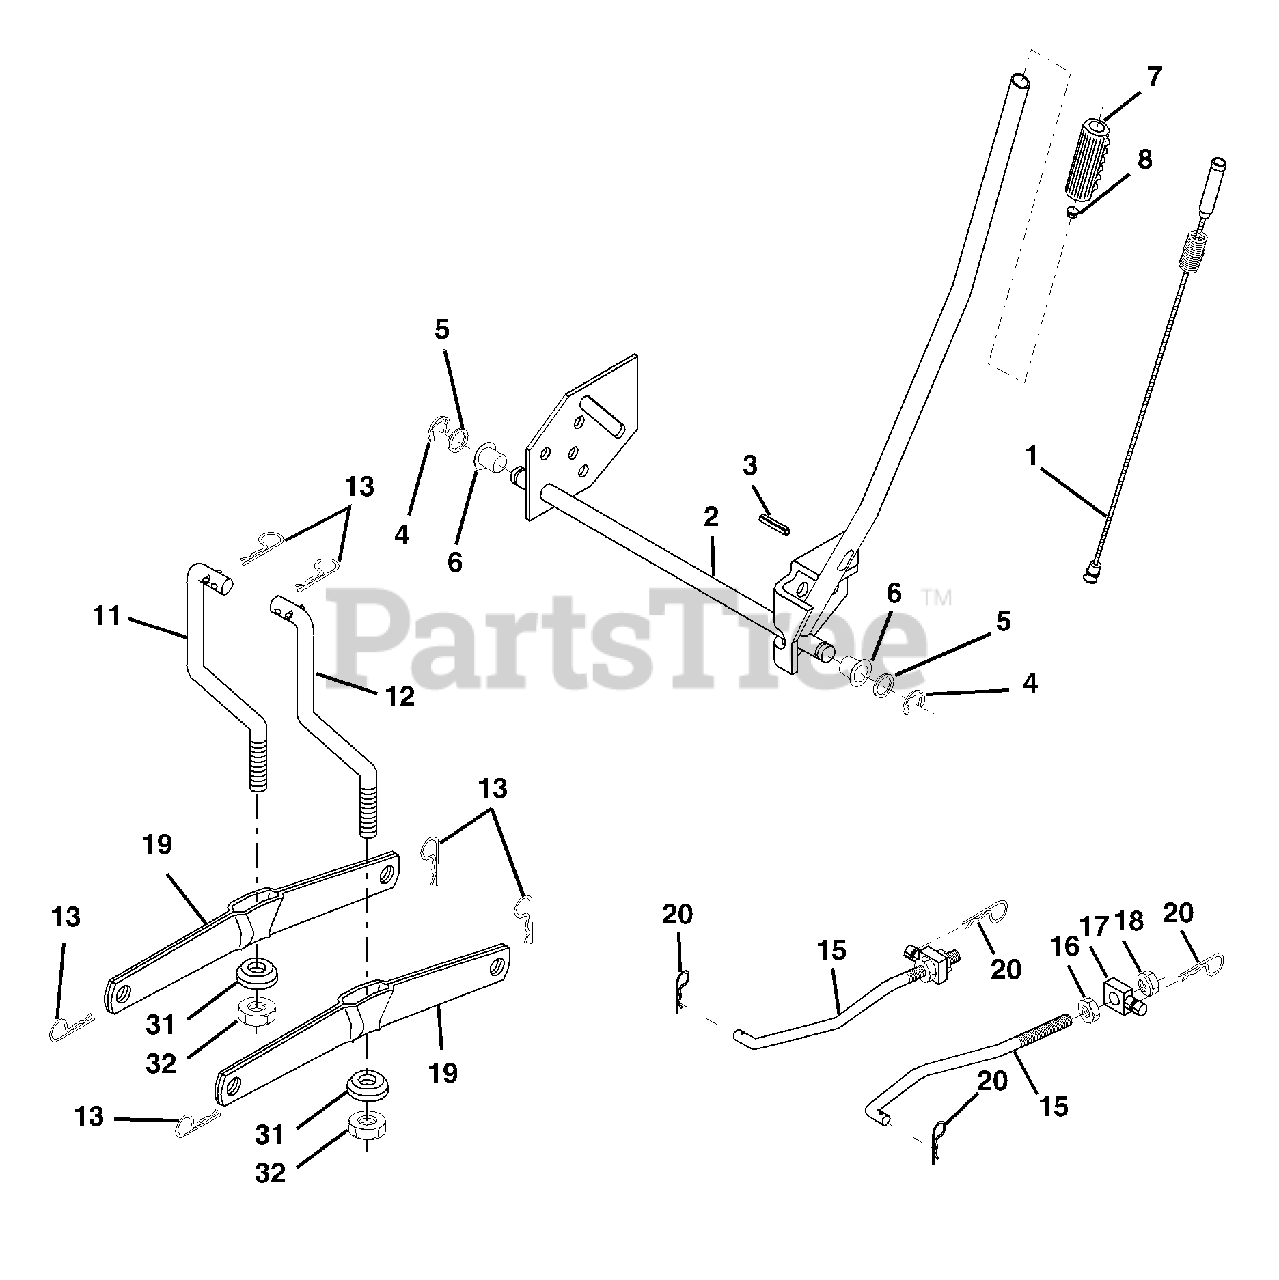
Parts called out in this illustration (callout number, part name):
1	Wire Asm Inner/Sprg W/plunger
2	Shaft Asm Lift RH w/Inf
3	Pin Groove 5/16 Dia x 1.875
4	E Ring #5133-62
5	Washer 21/32 x 1 x 21 Ga.
6	Bearing Nylon Blk 629 Id
7	Grip Handle
8	Button Plunger
11	Link Lift LH Fixed Length
12	Link Lift RH Fixed Length
13	Retainer Spring
15	Link Front
16	Nut Jam Hex 1/2-13 unc
17	Trunnion
18	Nut Lock W/Wsh 1/2-13 unc
19	Arm Suspension Rear
20	Retainer Spring
31	Bearing Pvt Lift
32	Nut Crownlock 3/8 - 24
